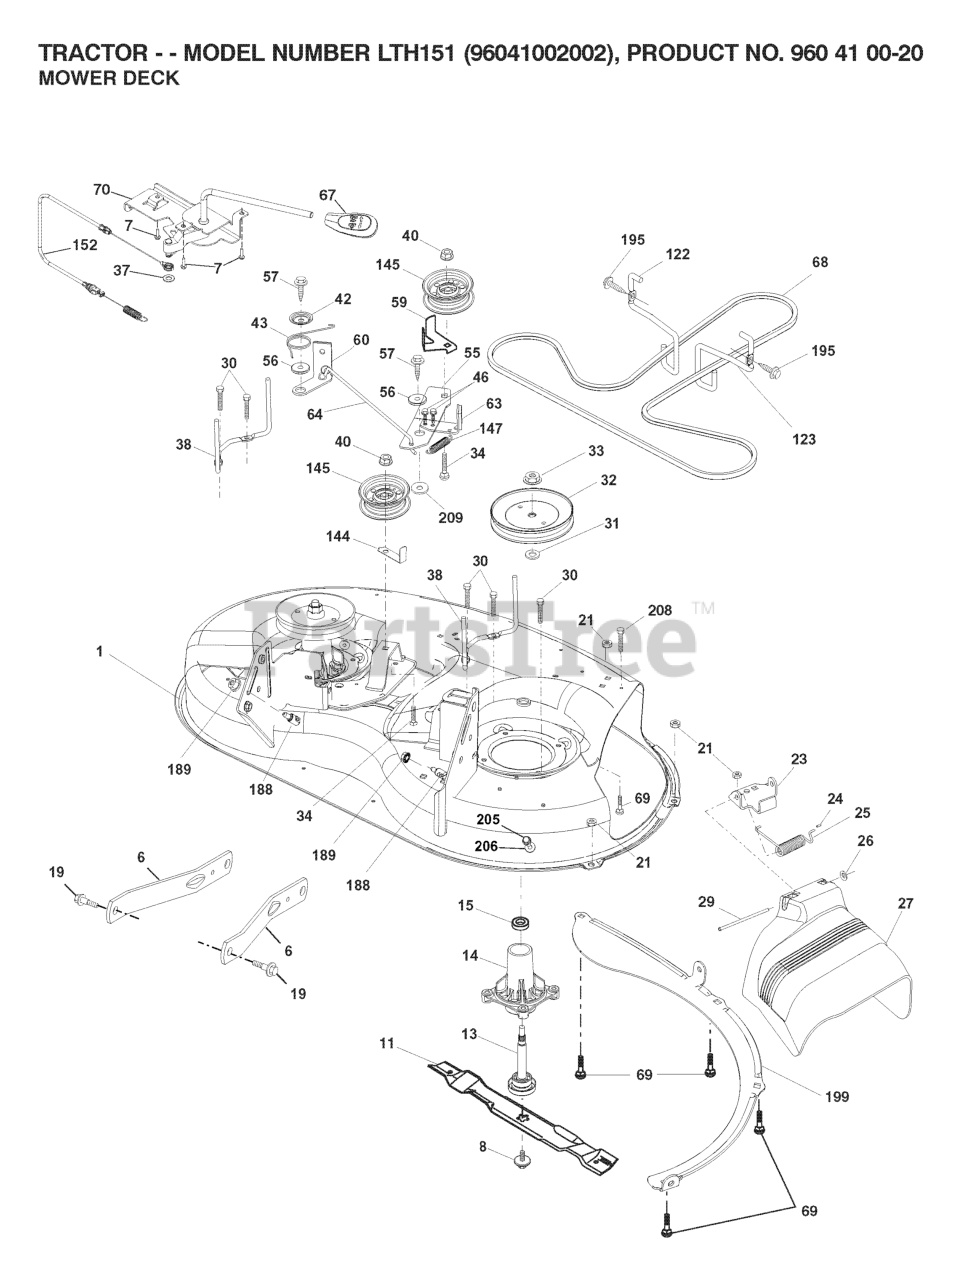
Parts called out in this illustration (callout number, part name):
1	HOUSING
6	ARM.SUSPENSION.MOWER.R
7	SCREW
8	BOLT.WASHER.ASM.7/16-2
11	BLADE 38" PREMIUM
13	SHAFT.ASM.MDRL.N/GREASE.38
14	RP.HOUSING.MANDREL.4PT.
19	BOLT.SHOULDER
21	LOCKNUT
23	BRKT.DEFLECTOR.38"2005+
24	CAP-SLEEVE LT
25	SPRING.TORSION.DEFLECT
26	NUT PUSH M
27	SHIELD ASM.DFLCTR MWR.38-7"BLK
29	ROD.HINGE
30	SCREW, WASHER HEAD
31	WASHER.SPACER.MANDREL
32	PULLEY.MANDREL.5.0.PD.38"
33	NUT.FLANGE.LOCK.TOP
34	BOLT.3/8-16X1.50
37	WASHER
38	KEEPER BELT LH MANDREL
40	NUT LOCK FLG 3/8-16 UNC
42	SPRING.TORSION.BRAKE
43	SRPING.TORSION.RETAINE
46	SCREW.1/4-20X5/8
56	SPACER.RETAINER
57	SCREW 3/8-16X1
59	GUARD, BELT
60	RP ARM.BRAKE.MOWER.38"LH.TEX
63	ARM BRAKE MOWER RH 38"
64	LINK BRAKE
67	HANDLE.CLUTCH.CABLE.LT
69	BOLT
70	CLUTCH.ASM.MANUAL.LT.PRED
122	KEEPER BELT ENGINE LH
123	KEEPER BELT RH
144	KEEPER BELT
145	PULLEY.IDLER.48"PRIMARY
147	SPRING RETURN
152	CLUTCH CABLE
188	STUD.FASTNER.W/ANTI-ROTATE
189	NUT LOCK HEX FLANGE 5/16-18
195	SCREW, 3/8-16X3/4
199	BAFFLE.VORTEX.FRONT.38"
205	SCREW
208	SCREW 3/8-16X1/2
209	WASHER 12/32X2X10GA
